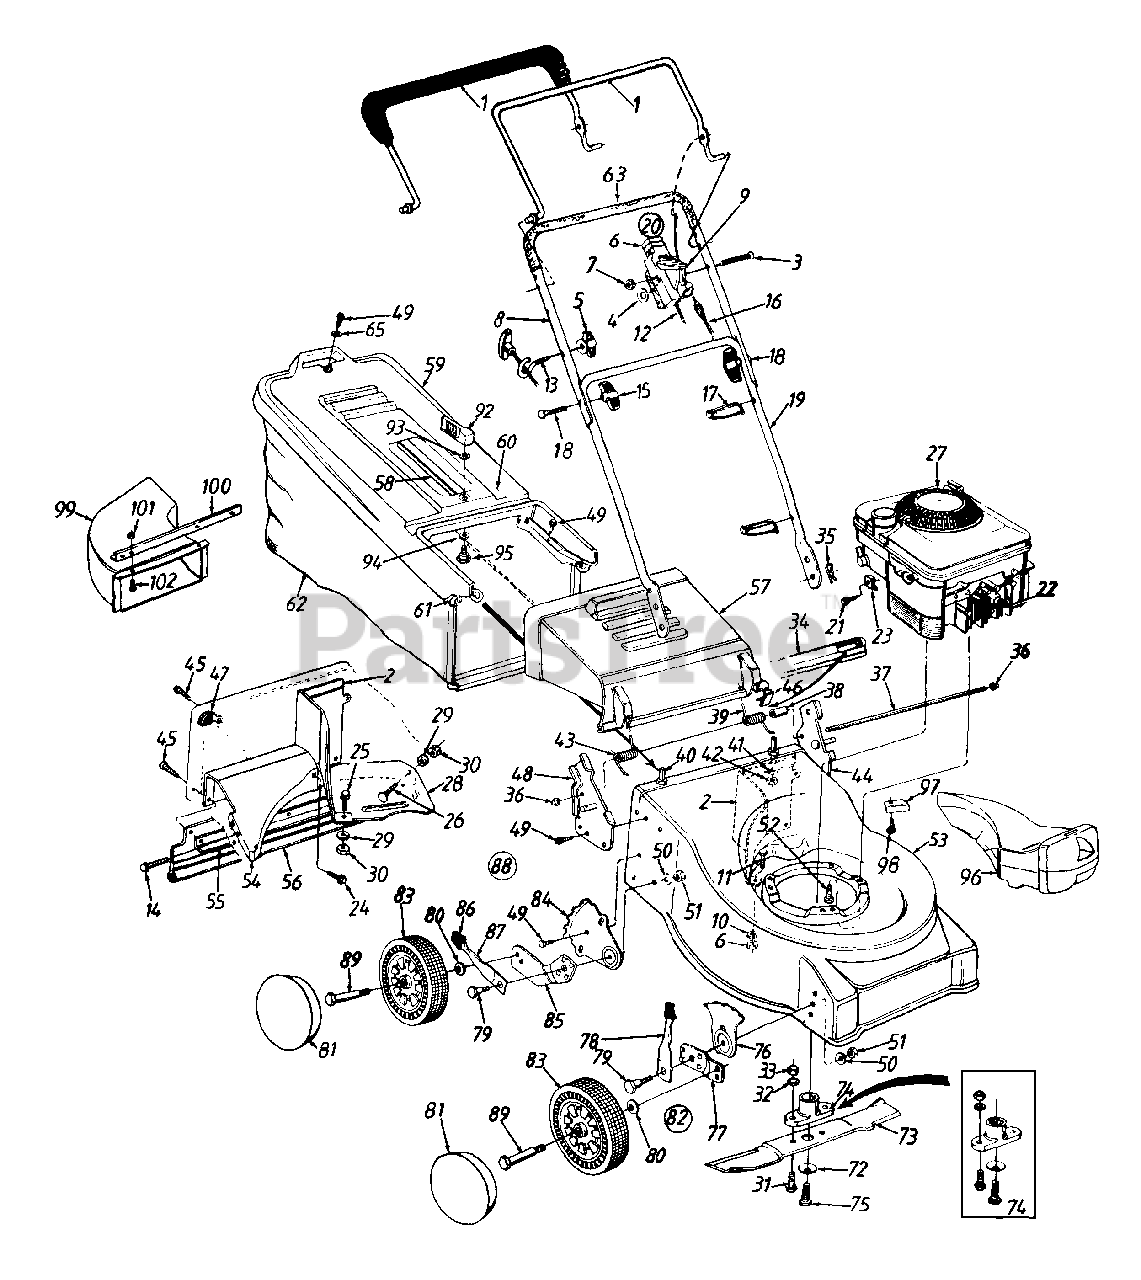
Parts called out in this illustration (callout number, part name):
4	Spr. Wash. .66" I.D.
5	Handle Knob 1/4-20 Thd.
6	Throttle Body
7	Hex L-Nut 1/4-20 Thd.
10	Bell-Wash. 1/4" I.D.
11	Hex Bolt 1/4-20 x .85"
12	Throttle Control Wire - 55"
13	Rope Guide
14	Hex B-Tap Scr. 1/4 x .38" Lg.
15	Hand Knob
16	Control Cable - 40.5"
17	Cable Tie
18	Curved Hd. Bolt 5/16-18 x 2" Lg.
20	Throttle Box Comp.
21	Hex Self-Tap Scr. #10-32 x .62" Lg.
22	Spark Plug Boot
23	Cable Clamp
24	Hex 8-Tap Scr. 1/4 x .38" Lg.
25	Hex Bolt 1/4-20 x .85" Lg.
26	Carriage Bolt 1/4-20 x .5" Lg.
27	Engine
30	Hex Nut 1/4-20 Thd.
31	Hex Bolt 3/8-24 x 1" Lg.
32	L-Wash. 3/8" I.D.
33	Hex Nut 3/8-24 Thd.
34	Seal - Extrusion
35	Int. Cotter Pin 5/16" Dia.
36	Cap Speed Nut
37	Hinge Pin 17.75" Lg.
38	Spacer .255" I.D.
39	Torsion Spring - L.H.
40	Shld. Pin 3/8-24 x 1.43" Lg.
41	L-Wash. 3/8" I.D.
42	Hex Jam Nut 3/8-24 Thd.
43	Torsion Spring - R.H.
46	Deflector Plug
47	Corner Plug
50	Bell-Wash. .39" I.D.
51	Hex Nut 3/8-16 Thd."
52	Hex L-Wash. Hd. Scr. 3/8-16 x 1" Lg.
57	Rear Chute Deflector
58	Hardtop Handle
59	Hardtop Bag Cover
60	Rear Catcher Frame
62	Grass Bag
63	Foam Grip
65	Fl-Wash. .281" I.D.
72	Bell-Wash. .39" I.D.
73	21" Blade
74	Blade Adapter Kit
75	Hex Bolt 3/8-24 x 1.5" Lg.
76	Height Adj. Plate
78	Spring Lever Ass'y. w/Knob
79	Shld. Bolt .50" Dia. x .357"
80	Bell-Wash. .38" I.D. x .88" O.D.
81	Hub Cap (5-1/2" Dia.)
82	Height Adj. Ass'y. Comp. - R.H.
83	Wheel Ass'y. Comp.
84	Index Plate
85	Pivot Bar - R.H.
86	Spring Lever Knob
87	Spring Lever
88	Rear Height Adj. Ass'y. Comp. - R.H.
89	Axle Bolt
92	Grass Catcher Locking Knob
93	Internal L-Wash. 1/4" I.D.
94	Wave Washer 3/8" I.D.
95	Shld. Bolt .342" Dia. x .268"
96	Mulching Plug
97	Stop Bracket
98	Hex Tap Scr. 3/8-16 x .75" Lg.
99	Chute Deflector
101	Hex L-Nut 1/4-20 Thd.
102	Mach. Scr. 1/4-20 x .5" Lg.
